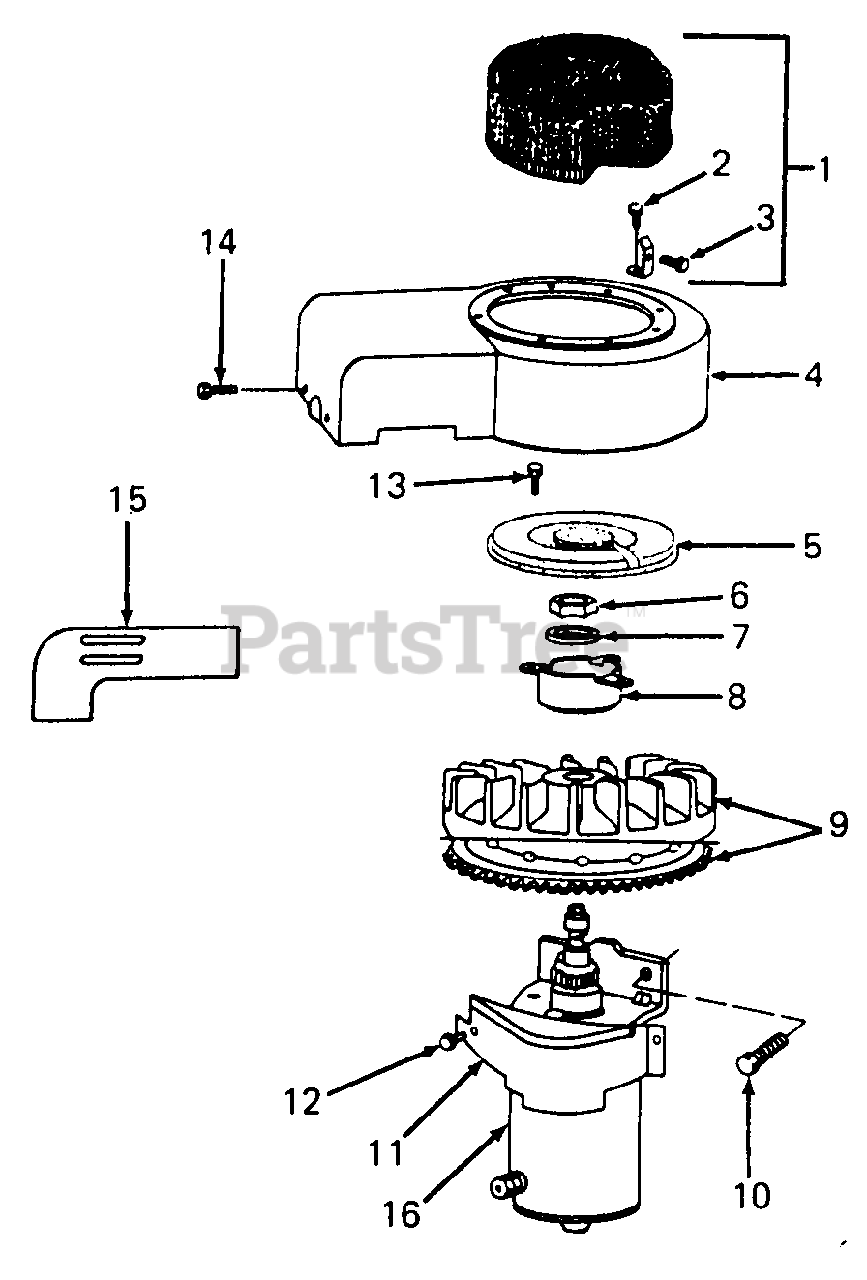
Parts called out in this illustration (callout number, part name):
1	Guard, Debris
3	Screw
4	Housing, Blower
5	Screen, Flush Rotating
6	Nut, Flywheel
7	Washer, Spring
8	Cup, Screen Mounting
9	Flywheel & Ring Gear
10	Screw Sem
11	Cover, Starter
12	Screw Sem
13	Screw Sem
14	Screw, Blower Housing Mtg Sem
15	Guide, Air
16	Starter Motor
